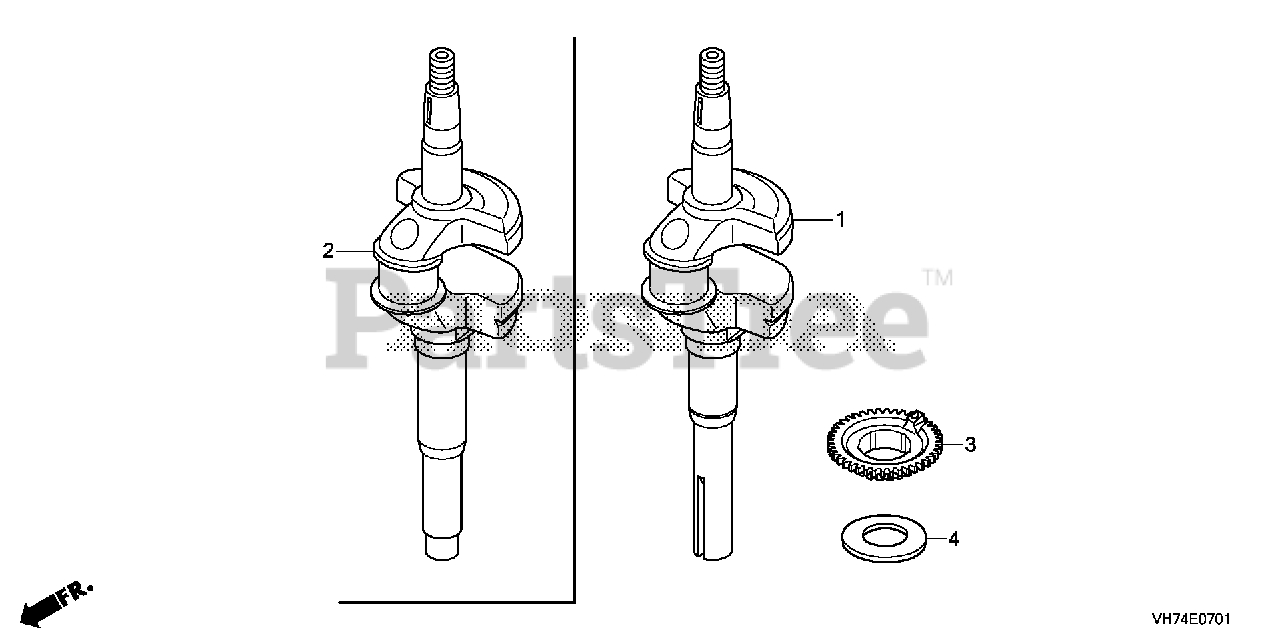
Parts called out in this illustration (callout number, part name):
1	CRANKSHAFT
3	PULLEY, TIMING BELT DRIVE
4	WASHER, THRUST
